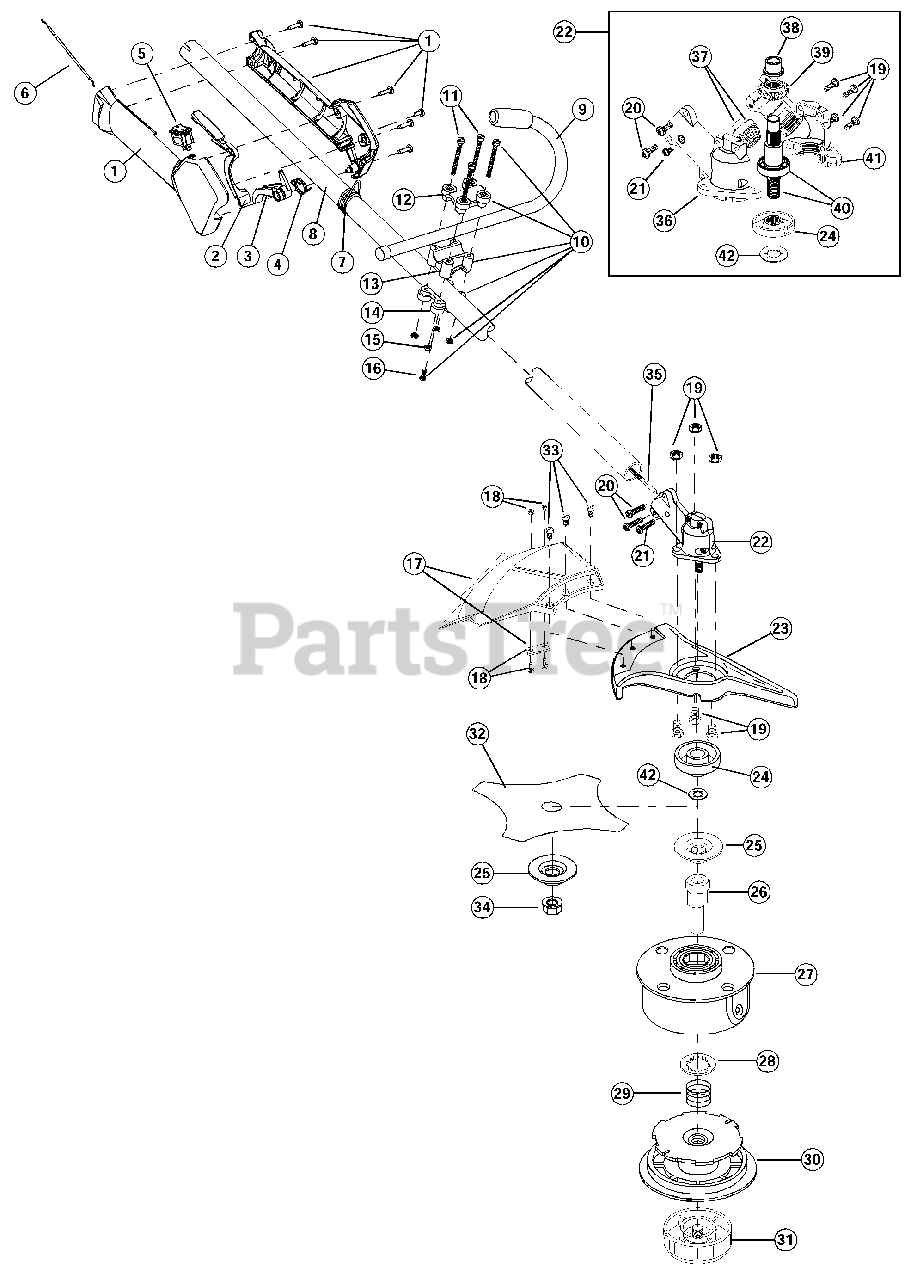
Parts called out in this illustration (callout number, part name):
1	Throttle Housing and Trigger Assembly
2	Throttle Trigger Lock-Out
3	Throttle Trigger
4	Throttle Trigger Spring
5	Switch Assembly
6	Throttle Cable Assembly
7	Harness Clip
8	Drive Shaft Housing Assembly
9	J-Handle Assembly
10	Handle Bracket Assembly
12	Upper Handle Clamp
13	Middle Handle Clamp
14	Lower Handle Clamp
16	Anti-Rotation Screw
17	Shield and Blade Assembly
18	Blade Assembly
19	Shield Mount Screw Assembly
20	Gearbox Mounting Hardware
21	Anti-Rotation Screw
22	Gearbox Assembly
23	Blade Shield
24	Blade Driver
25	Retaining Washer
26	Spool Shaft
27	Outer Spool and Eyelet Assembly
28	Retainer
29	Spring
30	Inner Reel
31	Bump Head Knob Assembly
32	4-Tooth Blade
33	Guard Mount Screws
34	Nut
35	Flexible Drive Shaft
36	Right Housing
37	Pinion Gear Assembly
38	Output Shaft Bushing
39	Output Shaft Gear
40	Output Shaft Assembly
41	Left Housing
42	Palnut
